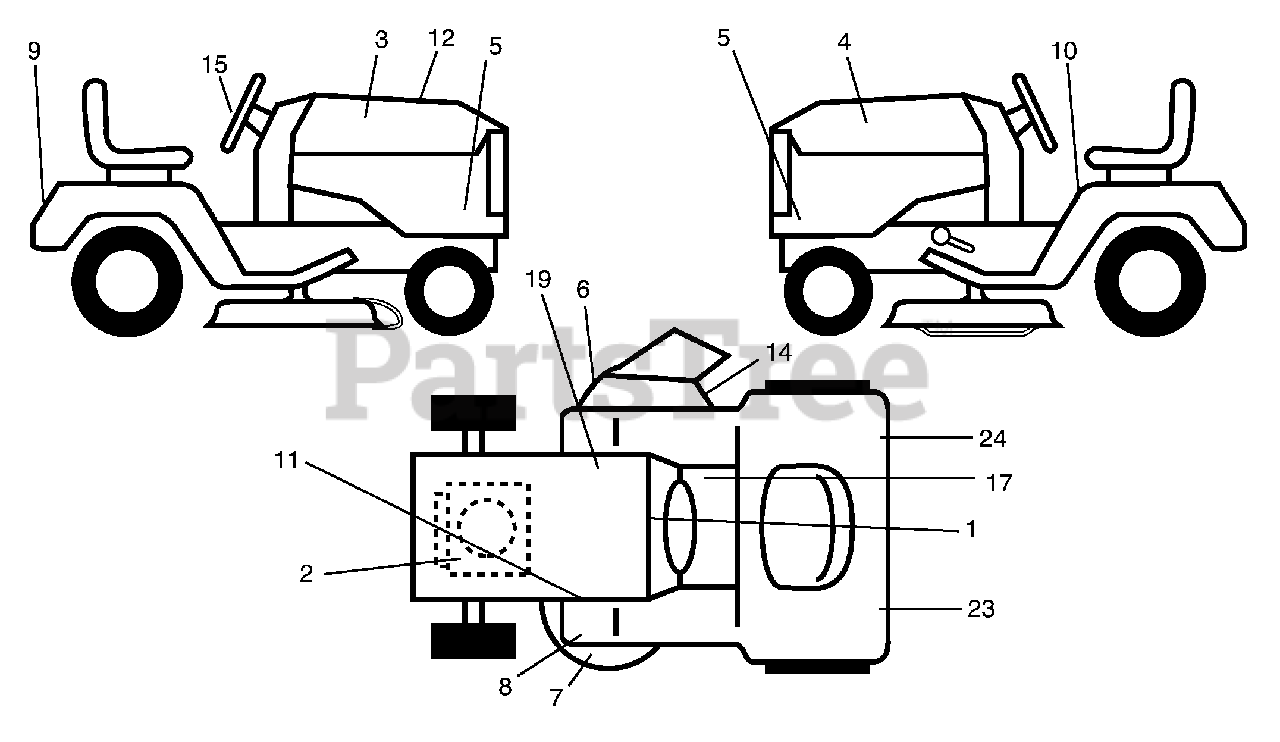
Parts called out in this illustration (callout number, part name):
1	Decal, Dash
3	Decal, Hood, RH
4	Decal, Hood, LH
5	Decal, Hood Sides
6	Decal, Warning
7	Decal, Upstop
8	Decal, Deck Caution
9	Decal
10	Decal, Danger
11	Ft. Rest
12	Decal, Repl.
14	Decal, V-Belt Schematic
15	Decal, Ins. Whl. Strg.
17	Decal, Saddle Brake Parking
19	Decal, Battery
23	Reflector, LH
24	Reflector, RH
